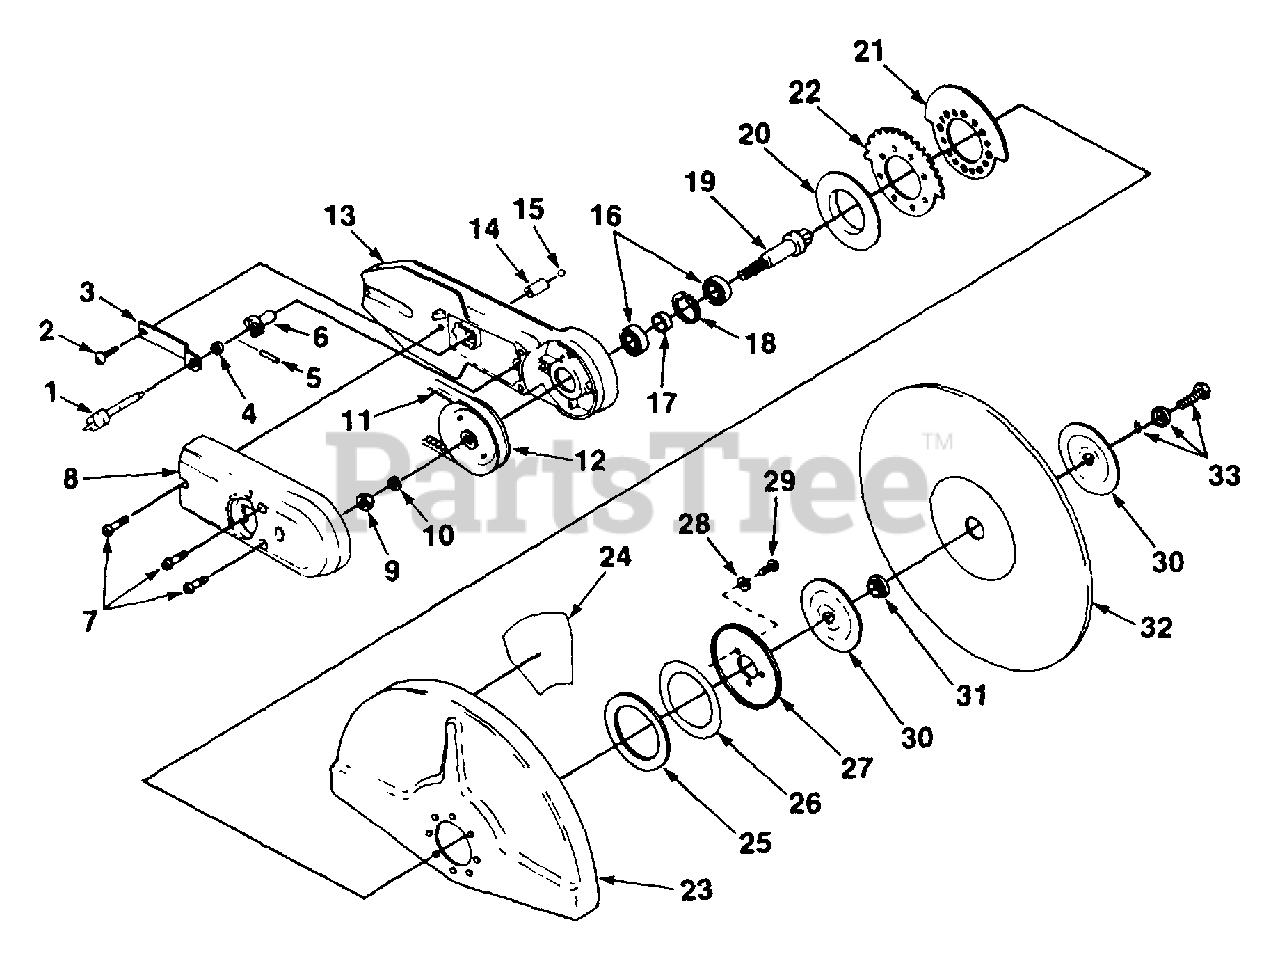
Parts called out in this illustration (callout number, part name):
1	KNOB & PIN
2	SCREW - Truss Hd (10-24 x 1/2")
3	PLATE Spring
4	SPACER - Adjusting Pin
5	PIN - Roll 1
6	SLEEVE - Cam
7	SCREW - Round Hd (10-24 x 23/32")
8	BELT - Cover
9	NUT - Hex
10	WASHER - Lock (7/16)
11	BELT - V-Drive
12	PULLEY & HUB
13	ARM - Wheel
14	SNUBBER
15	STEEL BALL
16	BEARING - Ball
17	SPACER - Bearing
18	RING - Retaining
19	SHAFT - Wheel
20	COLLAR - Wheel Guard
21	PAD - Adjuster
22	DETENT - Adjuster
23	WHEEL GUARD & DECAL - 12"
23	WHEEL GUARD & DECAL - 14"
24	DECAL - Caution
25	WASHER - Rubber
26	SHIM - .020"
26	SHIM - .030"
27	WASHER - Spring
28	WASHER (#12 - 11/16)
29	SCREW - Truss Hd (10-24 x 1/2")
30	FLANGE - Wheel
31	SPACER (1")
32	WHEEL
33	BOLT & WASHER
